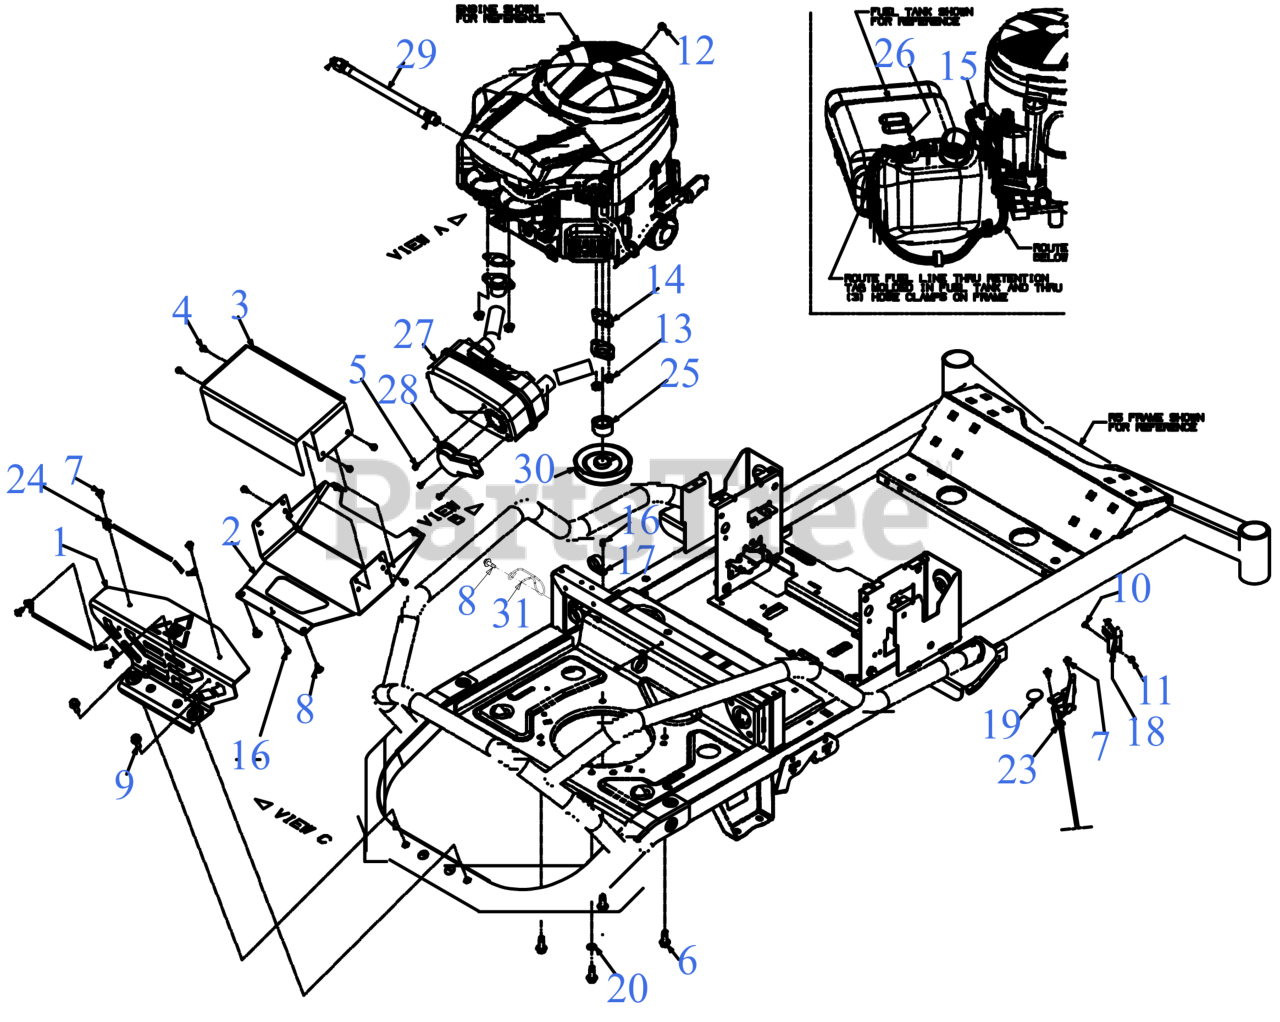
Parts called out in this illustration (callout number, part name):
1	MUFFLER COVER (REAR) (BLACK)
2	MUFFLER SHIELD (LOWER)
3	MUFFLER SHIELD (TOP)
4	HEX SCREW AB-TAP #10 x .50
5	HEX SCREW WASHER HD #8-18 x 0.500
6	SCREW 3/8-16 x 1
7	SCREW 1/4-20 x .5
8	SCREW M6-1 x .625
9	SCREW 5/16-18 x .875 GR5
10	SCREW #8-32X.38 LG
11	HEX NUT 8-32
12	HEX NUT 1/4-20
13	HEX FLANGE NUT M8X
14	MUFFLER GASKET
15	HOSE CLAMP 1/20
16	RATCHET CLIP (.188 x .85)
17	DRAIN HOSE CLAMP
18	THROTTLE CONTROL KNOB
19	CHOKE PLUG
20	LOCK WASHER 3/8
23	THROTTLE CABLE 38"
25	ENGINE PULLEY SPACER
26	FUEL HOSE LOW PERMEATION 45"
27	EXHAUST MUFFLER
28	EXHAUST DELECTOR (LONG)
29	OIL DRAIN HOSE (11.26" 3/8 NPT)
30	TRANSMISSION DRIVE PULLEY
31	HOSE GUIDE
